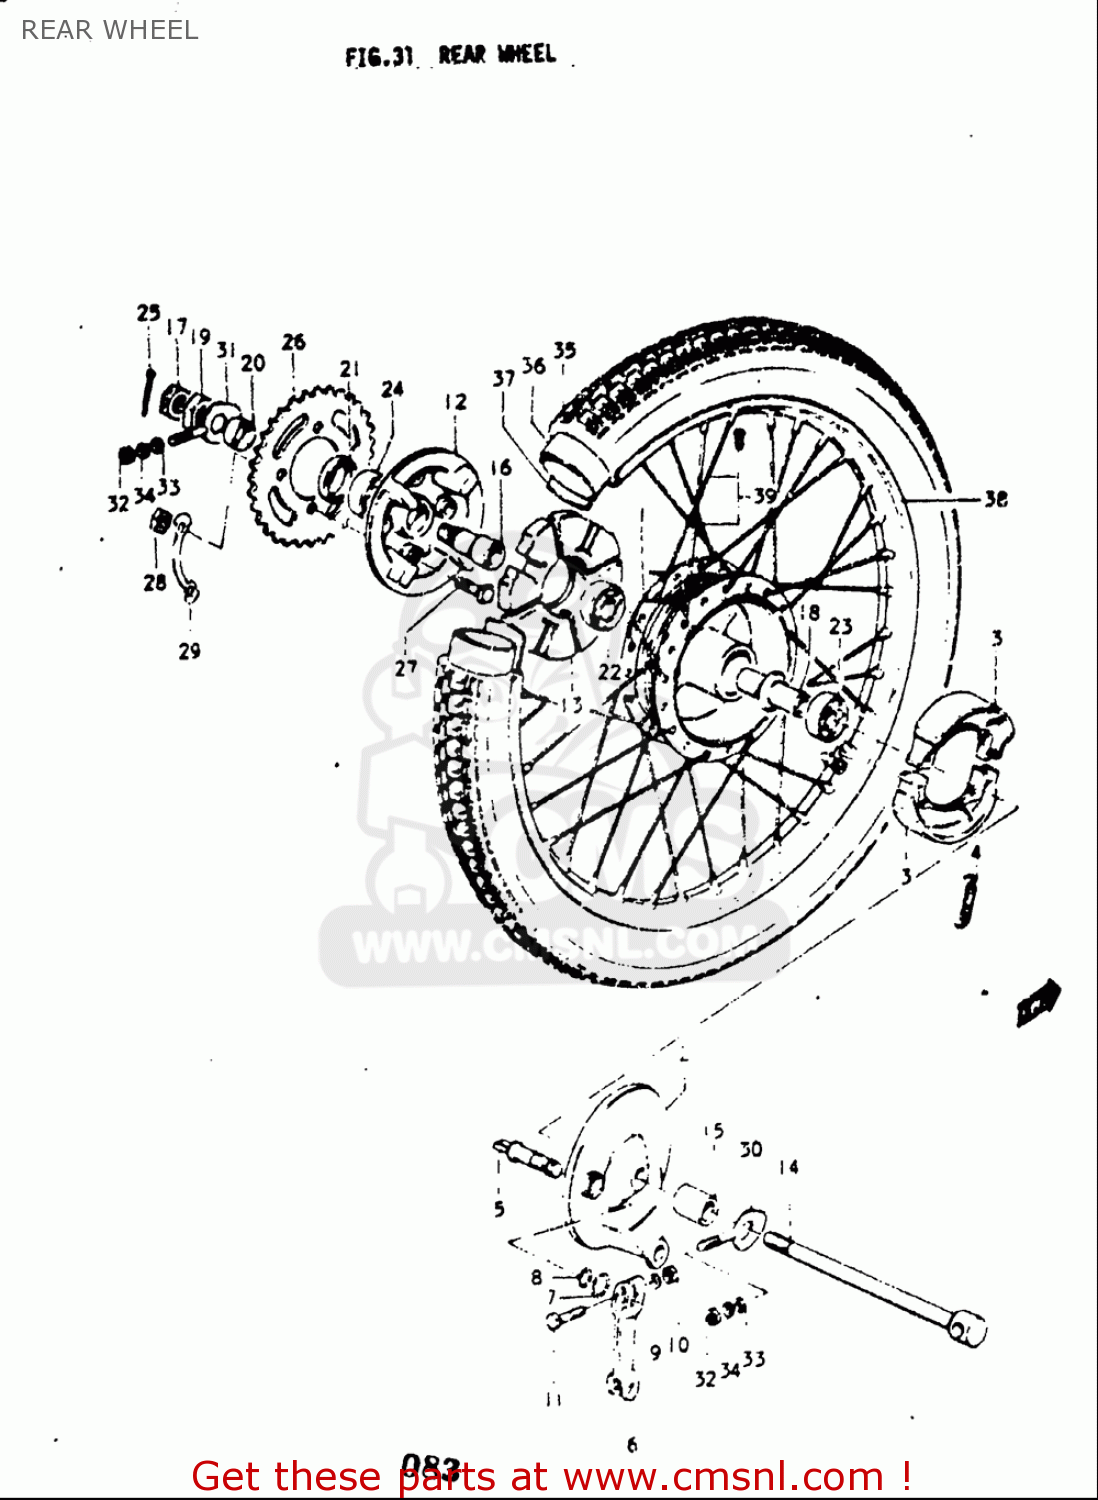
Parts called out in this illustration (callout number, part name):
3	SHOE & SPRING SET,BRAKE (NAS)
4	SPRING(L:35.8)
5	CAM,FR BRAKE
6	LEVER,RR BRAKE CAM
7	WASHER(12.5X20X1)
8	O RING(D:2.5,ID:11.4)
9	WASHER
10	NUT
11	BOLT(6X31)
12	DRUM,REAR SPROCKET MOUNT
13	ABSORBER,RR WHEEL HUB SHOCK
14	AXLE,RR
15	SPACER(12.2X22X30.5)
16	SHAFT,RR SPROCKET DRUM
17	NUT
19	NUT
20	SPACER(17X25X10.5)
21	SEAL,OIL(25X40X6)
22	BEARING
23	BEARING
24	BEARING(17X40X12)
25	COTTER PIN
26	SPROCKET,RR
27	BOLT(8X33.5)
28	NUT
29	WASHER
30	ADJUSTER,CHAIN,R
31	PLATE,CHAIN ADJUSTER
32	NUT
33	WASHER
34	WASHER,LOCK
36	TUBE ASSY,WHEEL INNER
37	PROTECTOR,INNER TUBE
38	RIM,WHEEL(1.40X18)
39	SPOKE SET,RR
